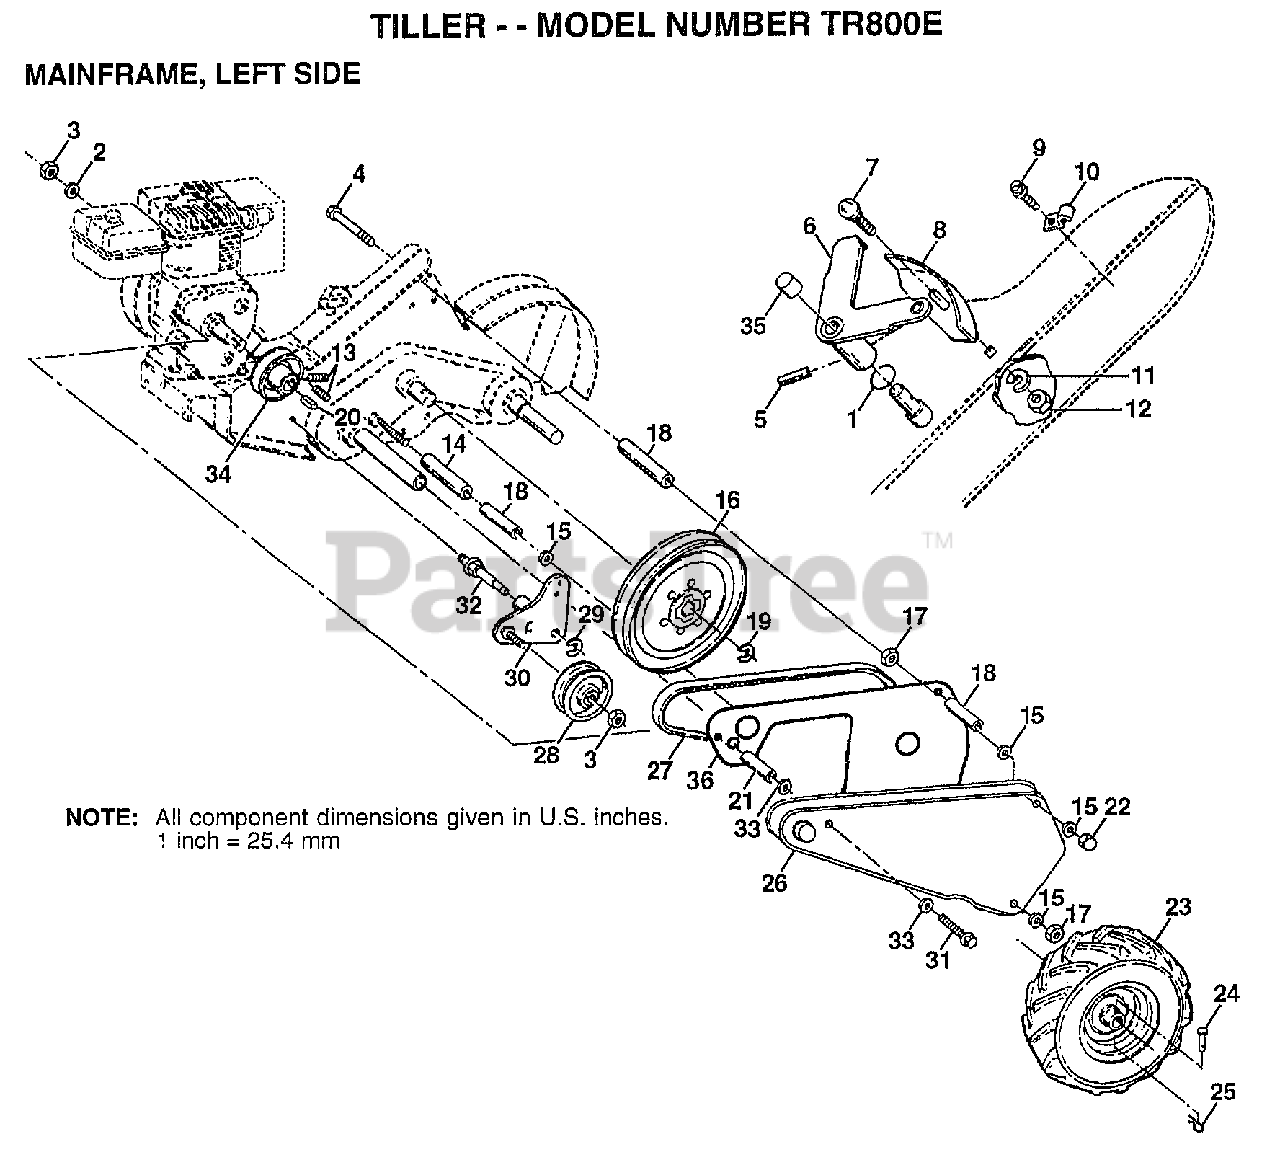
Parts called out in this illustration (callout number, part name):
1	O-RING TI
2	LOCKWASHER
3	NUT.HEX.3/8-16UNC
4	BOLT TI
6	LEVER ASM CRT
7	BOLT
8	PANEL TI
10	CONDIUT CLIP T
11	LOCKWASHER
13	SET SCREW
14	SPACER TI
15	WASHER
16	SHEAVE.TRANS.
17	NUT.HEX.5/16-18
18	SPACER TI
20	KEY TI
21	SPACER.SPLIT
22	NUT TI
23	TIRE TI
23	RIM.16X4X8.WHT
24	RIVET.PAN HD.1.75
26	GUARD.PNT.BELT.
27	BELT.DRIVE
28	PULLEY-IDLER TI
29	KLIP RING
30	BRACKET ASM IDLER
31	BOLT1/2-20UNF2.75
32	SHAFT.IDLER
34	SHEAVE CRT
35	CAP PLUNGER BLACK
